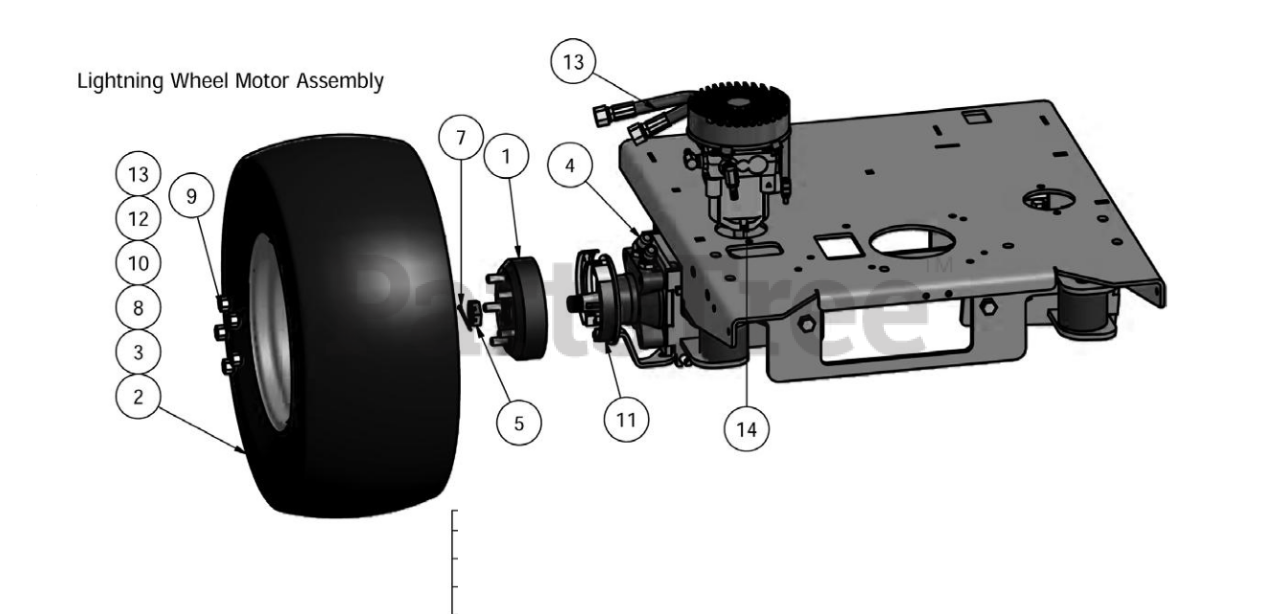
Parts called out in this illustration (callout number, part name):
1	Brake Drum
2	24" Tire and Wheel Assembly
3	12" Rim - 60"&72" Cut
4	Hydraulic Fitting (Wheel Motor)
5	Castle Nut
6	1/8"x2 1/4" Cotter Pin
7	24x12-12 Tire 60"&72" Cut
9	23x10.50-12 Tire & Wheel
10	Brake Pads
11	23x10.50-12 Tire
12	12" Rim 48" & 52" Cut
13	Hydraulic Hose for 48", 52", 60"
13A	Hydraulic Hose for 72"
14	Left Lightning Pump
14A	Right Lightning Pump
